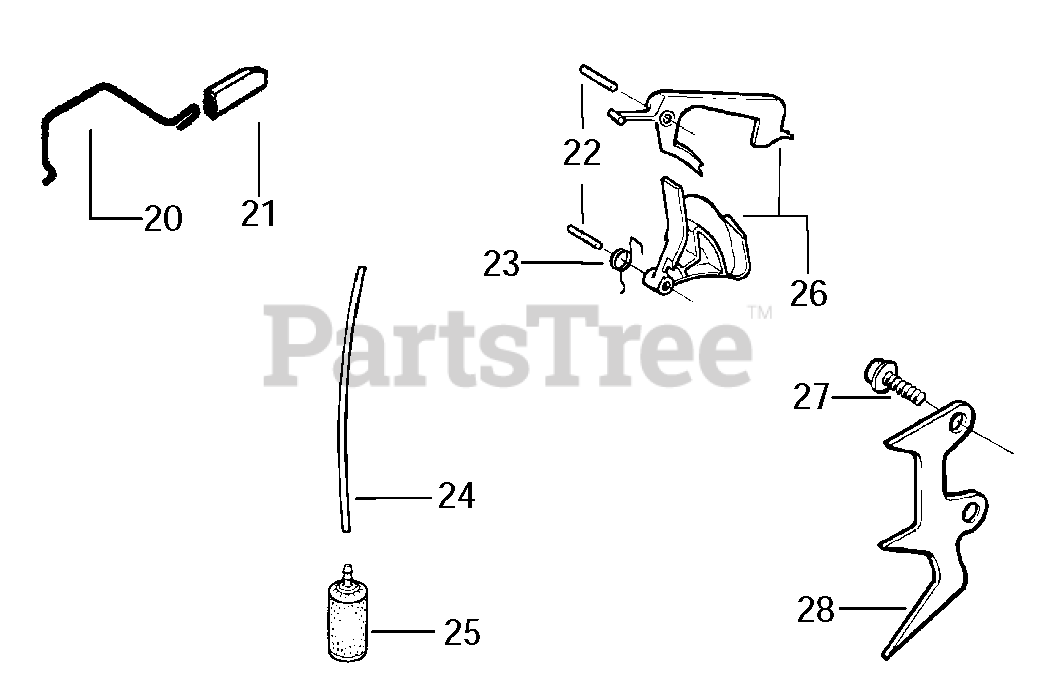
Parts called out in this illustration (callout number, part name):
20	THROTTLE SHAFT 36/41
21	THROTTLE ACTUATOR 36/41
22	PIN,TRIGGER 36/41
23	SPRING STR DOG
24	HOSE. FUEL
25	FUEL PICK-UP
26	THROTTLE TRIGGER-KIT
27	SCREW-10-14 X 1/2 PLASTITE
28	SPIKE 36/41
